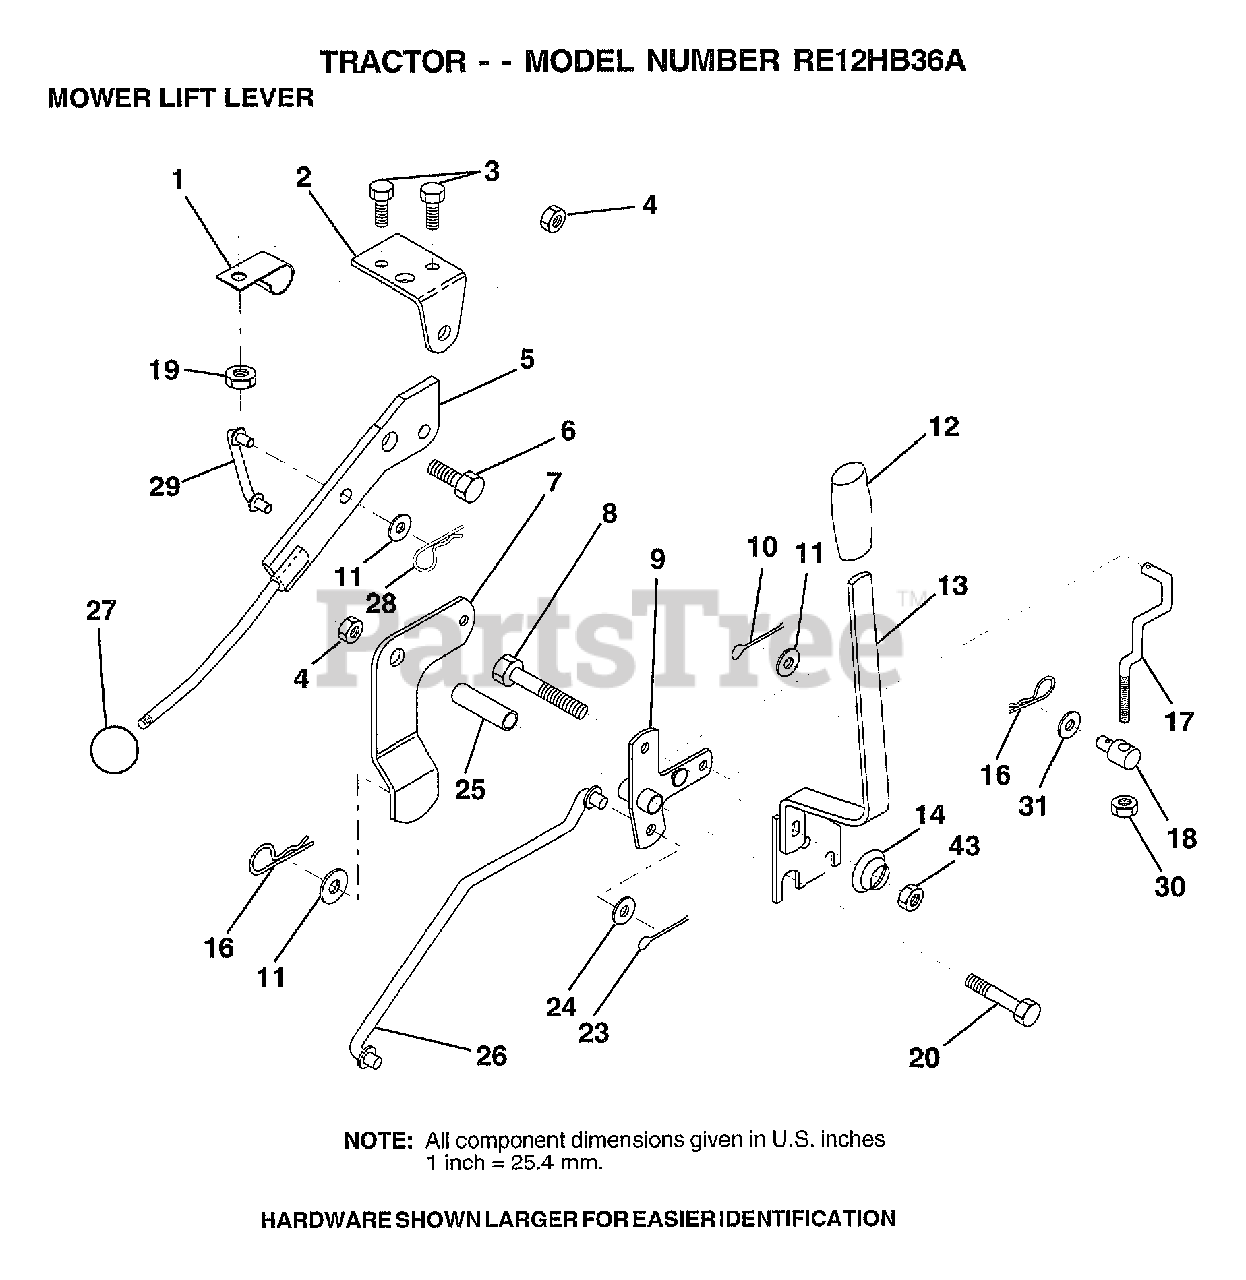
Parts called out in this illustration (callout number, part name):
1	"CLIP,INSULATOR"
2	BRKT CLUTCH
3	BOLT HXHD FIN
5	LEVER.ASM.CLUTCH
6	"BOLT, SHOULDER LT"
7	MWR CLUTCH ARM AS
8	BOLT
9	"BELLCRANK,LIFT"
10	COTTER PIN
11	WASHER
13	HANDLE.ASM.LIFT
14	SPRING COMPRESSIO
16	SPRING.RETAINER
17	"LINK,LIFT FRT"
18	TRUNION ADJ
20	BOLT
23	PIN COTTER 1/8
25	TUBE SPACER
26	ROD LIFT MOWER
27	KNOB T(3/8 HOLE)
28	RETAINER M
29	CLUTCH LINK
30	NUT
31	WASHER
